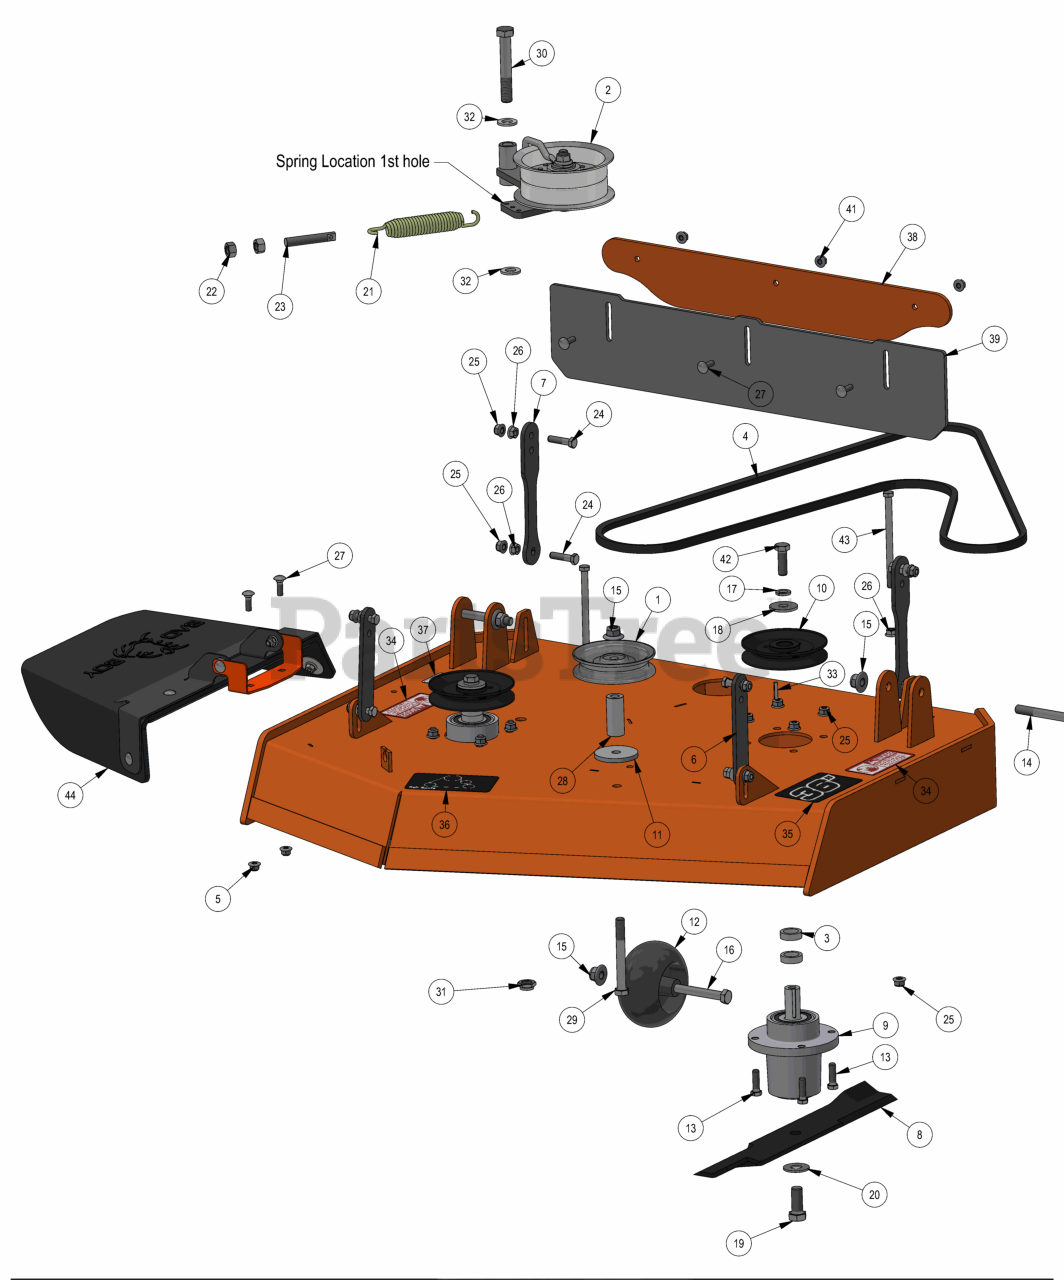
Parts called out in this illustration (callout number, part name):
1	5 V Idler Pulley 1/2" Bore
2	2020 36" Revolt Deck Idler Assembly
3	36 Deck Spindle Spacer
4	2020 Walk-Behind 36 Deck Belt
5	5/16" Nylock Flange Nut Zinc
6	2019 Revolt Front Deck Hanger
7	2019 Stand-On Rear Deck Hanger
8	52" Deck Fusion Blade
9	36'' Revolt Spindle Assembly
10	MZ Deck Pulley
11	MZ Deck Idler Spacer
12	2019 Deck Wheel
13	3/8-16 X 1-1/4 HEX CAP SCREW (GR.5) ZINC
14	1/2-13 X 3-1/2 HEX CAP SCREW (GR.5) ZINC
15	1/2-13 NYLON INSERT FLANGE LOCKNUT ZINC
16	1/2-13 X 4-1/2 HEX CAP SCREW (GR.5) ZINC
17	1/2 SPLIT LOCKWASHER (GR.8) ZINC/YELLOW
18	1/2 BELLEVILLE WASHER (1-5/8 OD X .140 THK) ZINC
19	5/8-18 X 1-1/2 HEX CAP SCREW (GR.8) ZINC YELLOW
20	5/8 USS FLAT WASHER (1-3/4" OD) GR.8 ZINC YELLOW
21	2009 Deck/Pump Idler Spring
22	1/2-13 HEX NUT ZINC
23	All Thread
24	3/8-16 X 1-1/2 HEX CAP SCREW (GR.5) ZINC
25	3/8" Nylock Flange Nut
26	3/8-16 HEX SERRATED FLANGE NUT HARD/ZINC
27	5/16-18 X 1 CARRIAGE BOLT (GR.8) ZINC
28	2019 Revolt Stationary Idle Spacer
29	1/2-13 X 4-1/4 HEX CAP SCREW (GR.5) ZINC
30	5/8-11 X 4 HEX CAP SCREW (GR.8) ZINC YELLOW
31	5/8-11 NYLON INSERT JAM LOCKNUT ZINC
32	.630 ID Plastic Washer
33	3/16 X 1 SQ MACHINERY KEY 1018 STL ZINC
34	Danger Decal-Spindle/Discharge
35	2018 36" Deck Decal
36	Revolt Pump Belt Route Decal
37	Deck Impact Patent Decal 9591803
38	2023 4" & 5" Stripping Kit Plate
39	2023 MZ Stripping Kit Rubber
40	2023 36'' DECK
41	5/16" Flange Nut
42	1/2-20 X 1-1/2 HEX CAP SCREW (GR.5) ZINC
43	3/8-16 X 5-1/2 HEX CAP SCREW (GR.5) ZINC
44	2020 36 Stand On Discharge Assembly
